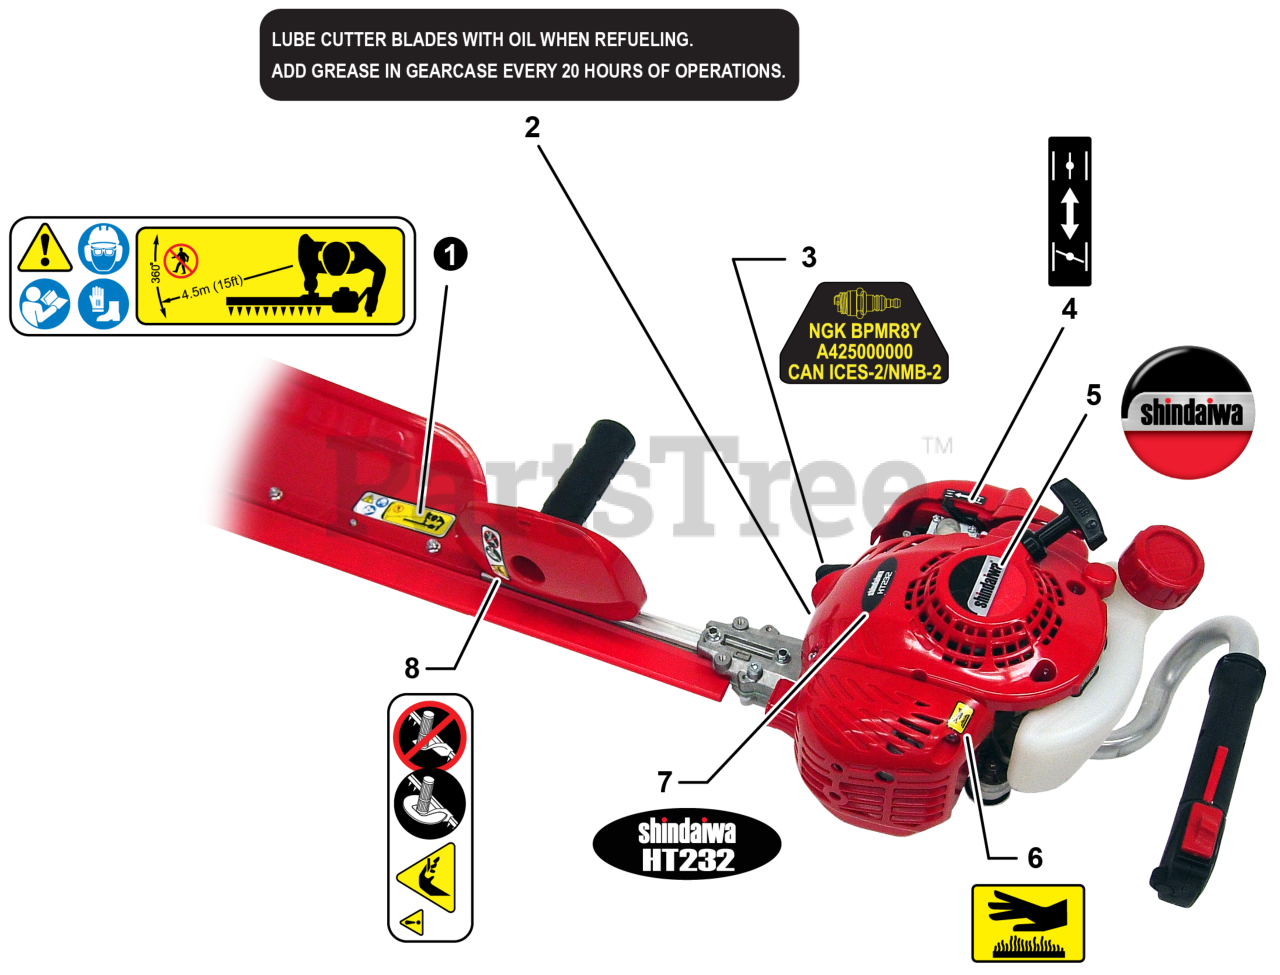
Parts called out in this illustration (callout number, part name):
1	LABEL - CAUTION
2	LABEL - LUBE BLADES
3	LABEL - SPARK PLUG - BPMR8Y
4	LABEL - CHOKE
5	LABEL - SHINDAIWA
6	LABEL - CAUTION - HOT
7	LABEL HT232
8	LABEL - CAUTION - ISO
